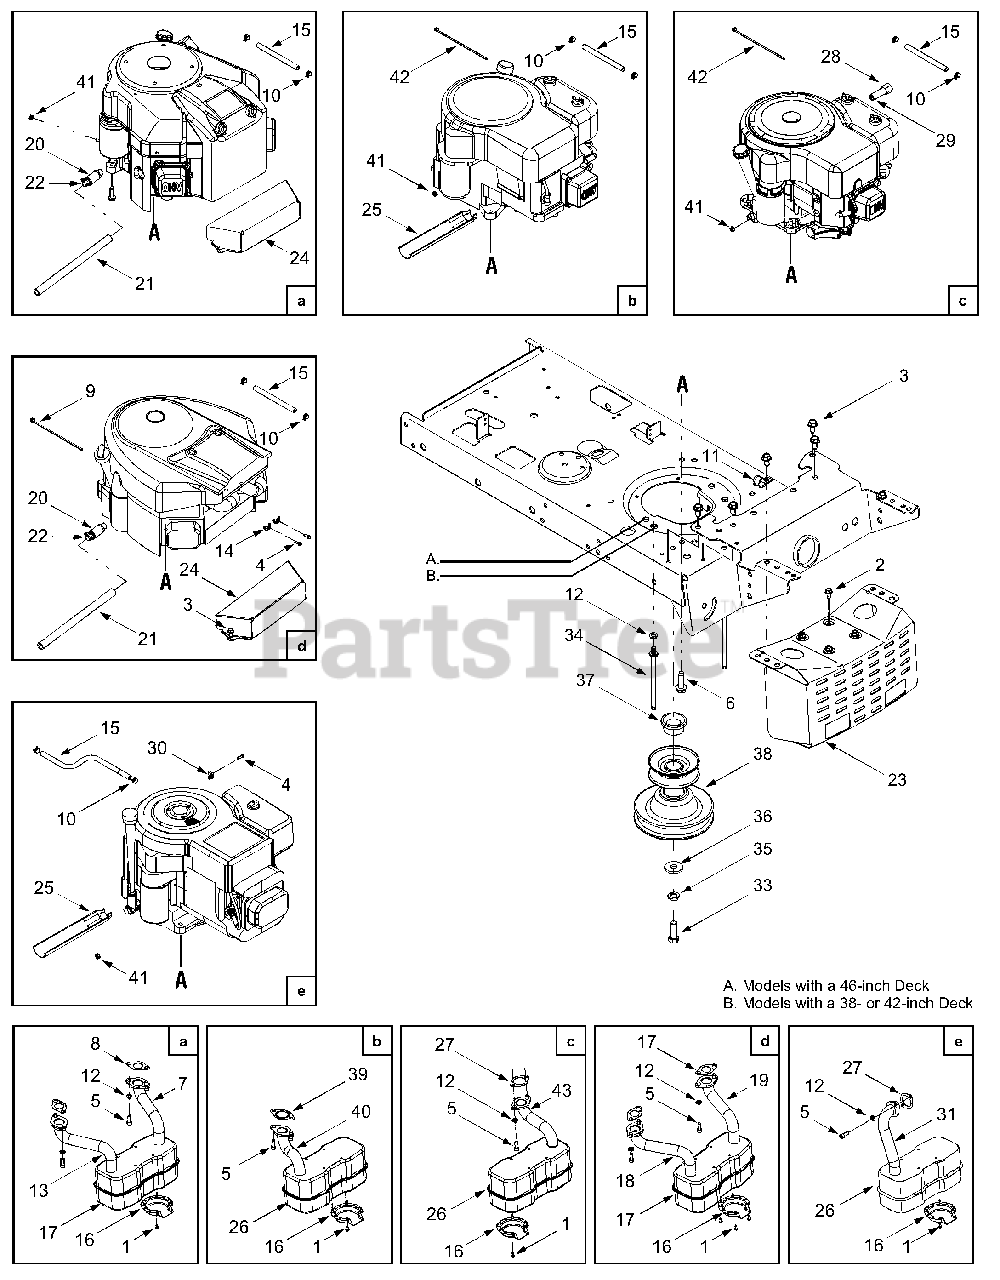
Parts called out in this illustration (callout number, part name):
1	Screw, #8-32 x .375
2	Self-tapping Screw, 1/4-20 x .5
3	Self-tapping Screw, 5/16-12 x .75
4	Screw, #10-32 x .625
5	Socket Cap Screw, 5/16-18 x .625
6	Self-tapping Screw, 3/8-16 x 1.25
7	LH Exhaust Pipe
8	Exhaust Gasket
9	Push-mount Cable Tie, 7.5
10	Hose Clamp, .490
11	Clamp, 9/16
12	Lock Washer, 5/16
13	RH Exhaust Pipe
14	Casing Clamp
15	Fuel Line Hose
16	Muffler Deflector
17	Muffler, Twin Inlet
18	RH Exhaust Pipe
19	LH Exhaust Pipe
20	Oil Drain Valve
21	Oil Drain Hose
22	Oil Drain Cap
24	Engine Heat Shield
25	Oil Drain Sleeve
26	Muffer, Single Inlet
27	Exhaust Gasket
28	Oil Drain Cap, 3/8-18
29	Oil Drain Pipe, 3/8-16 x 2.0
30	Casing Clamp
31	Exhaust Pipe
32	Screw, #8-18 x .50
33	Hex Screw, 7/16-20 x 1.25
34	Belt Keeper Pin, 5/16 x 4.75
35	Lock Washer, 7/16
36	Flat Washer, .450 x 1.25 x .164
37	Spacer, 1.0 x 1.4 x .825
38	Engine Pulley, 3.12 x 5.56
39	Exhaust Gasket
40	Exhaust Pipe
41	Hex Sems Nut, 1/4-20
42	Cable Tie, 7.4"
43	Exhaust Pipe
